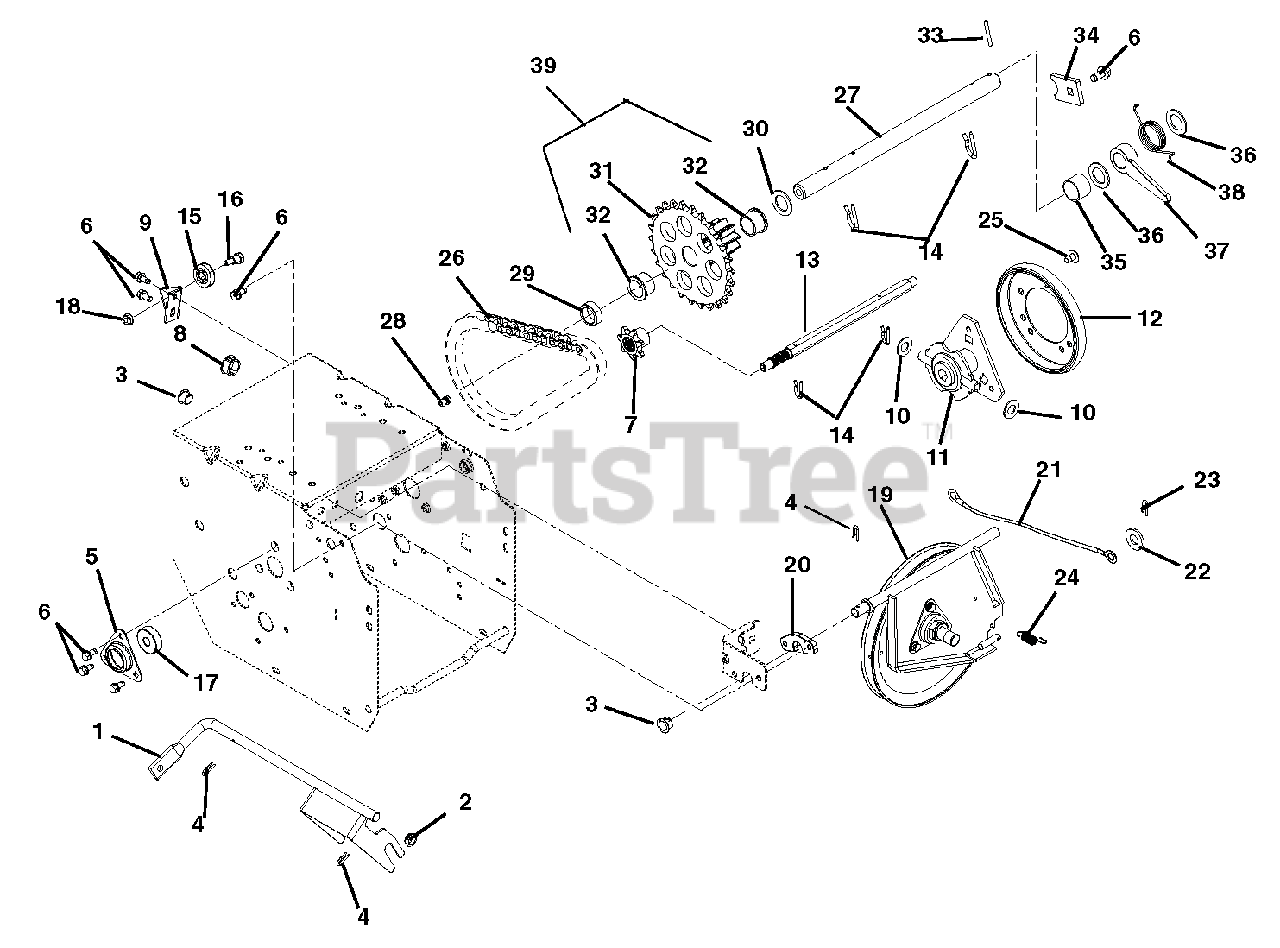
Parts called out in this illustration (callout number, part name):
1	WELDMENT, SHIFT FORK
2	BUSHING, POLYLINER-.50 SNAPIN
3	BUSHING, POLYLINER-.50 SPLIT
4	CLIP, SPRING
5	FLANGE, BEARING
6	SCR-TAP .25-20X.50 HWH TR YWZ
7	SPROCKET, PINION 7T W/SPLINE
8	PLUG, HOLE - .875" NYLON
9	BRACKET, CABLE PULLEY
10	WSHR-FL-STL .505X1.00X.062YWZC
11	CARRIER, DRIVE DISK
12	FRICTION, DISC
13	SHAFT, HEX W/SPLINE
14	PIN, SPRING CLIP
15	PULLEY, CABLE
16	BOLT, SHLDR-.375X.375X.25-20
17	BRG-BALL .437X1.375X.437
18	@NUT-LK-TOP-FLG .25-20 YWZC
19	PLATE, SWING - ASSEMBLY
20	SPACER, SWING GATE
21	CABLE, TRACTION - TRACTOR
22	@WSHR-FL-STL.344X.688X.065YWZC
23	PIN-HAIR INT .08X.18X1.18 YWZC
24	SPRING, EXT. .043X.438X1.64
25	SCR-TAP SERRDHDTX .31-18X.50BP
26	CHAIN - #41, 32 PITCHES
27	SHAFT, PINION
28	ZERK,FITTING .25X.125 DRIVE IN
29	BSHG-SLV, .635X.880X.305
30	WSHR-FL-STL .630X1.005X.062 YZ
31	PINION & SPROCKET
32	BSHG-FLG .625X.750X.500X.875
33	PIN-ROLL .125X1.00
34	TAB, ANTI ROTATION
35	SPACER, .635X.880X.611
36	WSHR-FL-STL .630X1.005X.062 YZ
37	LEVER, LOCK ARM
38	SPRING, TORSION
39	PINION & SPROCKET W/BUSHINGS
